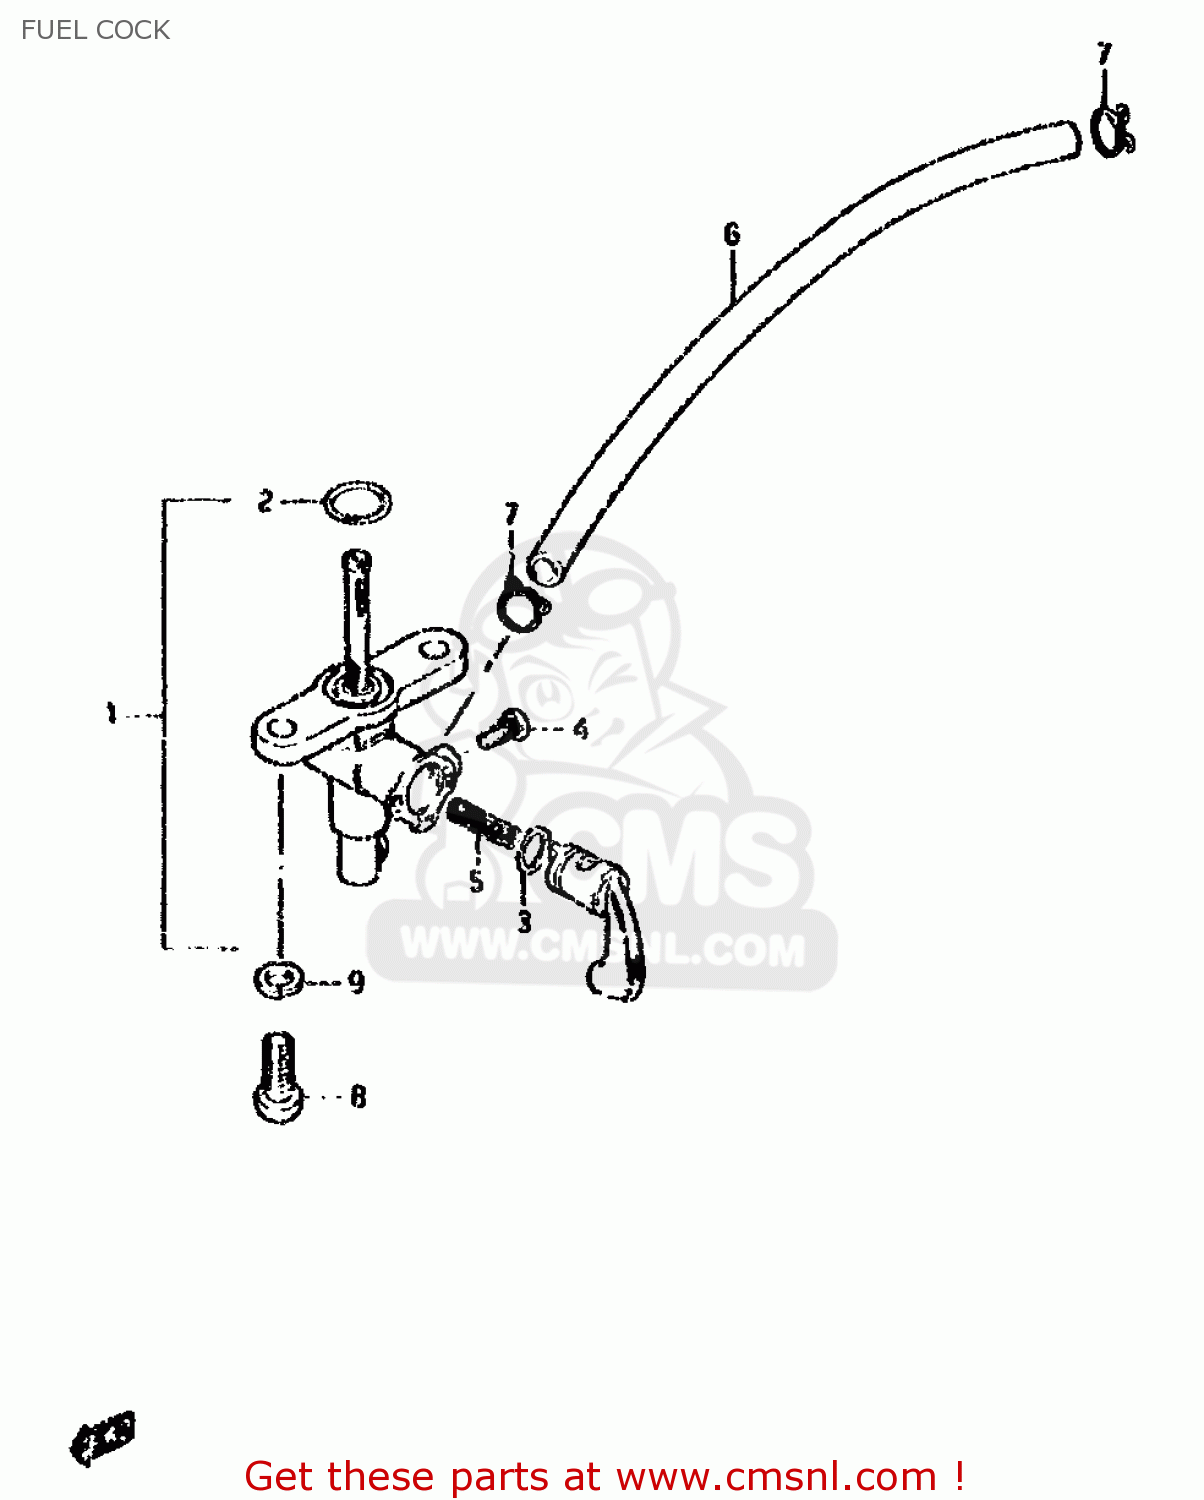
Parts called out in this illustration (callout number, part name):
1	COCK ASSY,FUEL
2	O RING
3	O RING,LEVER
4	SCREW
5	SPRING,FUEL COCK VALUE
6	HOSE(5X8.2X600)
7	CLIP
8	SCREW
9	WASHER,LOCK
